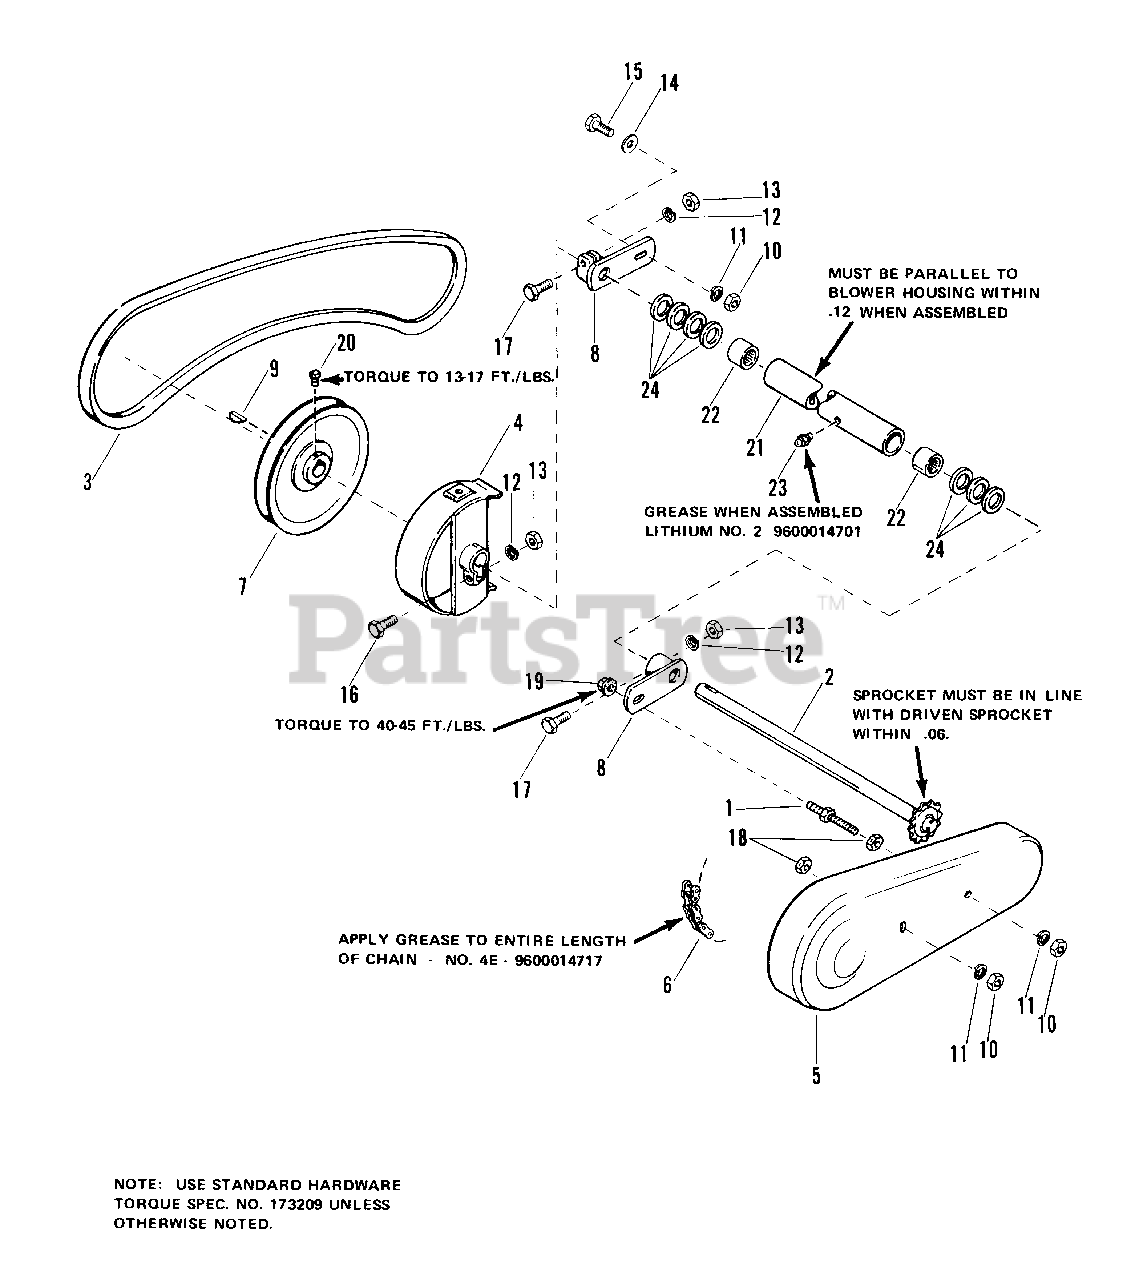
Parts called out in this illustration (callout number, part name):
2	SHAFT ASSEMBLY
3	V-BELT, 110.1"
4	GUARD, Belt
5	GUARD, Chain
8	CLAMP, Housing
9	KEY, Woodruff, No. 9, 3/16 x 3/4
10	NUT, 3/8-16
11	LOCKWASHER, 3/8
12	LOCKWASHER, 5/16
13	NUT, 5/16
14	WASHER, Plain, 3/8
15	CAPSCREW, Hex Hd., 3/8-16 x 1
16	CAPSCREW, Hex Hd., 5/16-18 x 1 1/2
17	CAPSCREW, Hex Hd., 5/16-18 x 1 3/4
18	NUT, Full Lock, 3/8-16
19	NUT, Flange Lock, 3/8-16
20	SETSCREW, Sq. Hd., 5/16-18 x 1/2
21	BEARING, Housing
22	BEARING, Needle
23	FITTING, Grease
